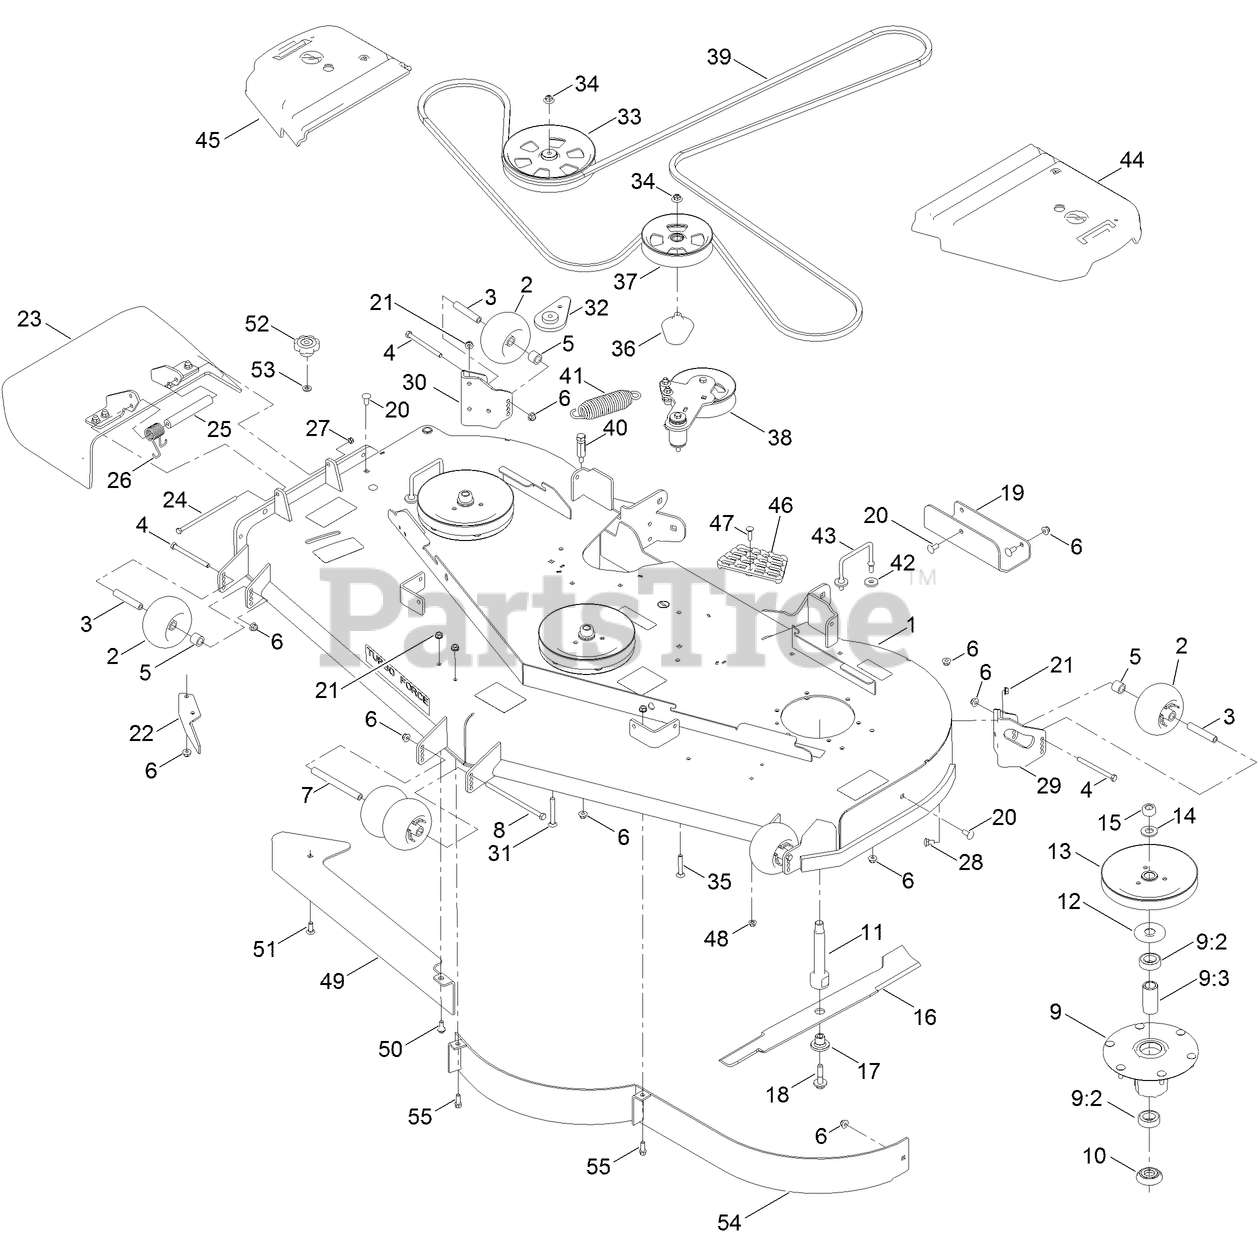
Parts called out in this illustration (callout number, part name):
1	DECK DECAL ASM
2	ROLLER-SCALP, ANTI
3	TUBE-SPANNER
4	SCREW-HH
5	TUBE-SPACER
6	NUT-HF, NI
7	SPACER-WHEEL
8	SCREW-HH
9	SPINDLE ASM
9:2	BEARING-BALL
9:3	SPACER-BEARING
10	GUARD-BOTTOM
11	SHAFT-SPINDLE
12	GUARD-BEARING, TOP
13	SHEAVE-DRIVE, BLADE
14	WASHER
15	NUT-HEX
17	BUSHING-HEX
18	SCREW-SEMS
19	PLATE-SKID
20	SCREW-CARR
21	NUT-HHF, WHIZ
22	BAFFLE-DISCHARGE
23	RUBBER DEFLECTOR ASM
24	SCREW-HH
25	SPACER
26	SPRING-TORSION
27	NUT-LOCK, NI
28	SCREW-CARR
29	MOUNT-WHEEL, LH
30	MOUNT-WHEEL, RH
31	SCREW-CARR
32	SPACER-IDLER
33	PULLEY-IDLER,FLAT
34	NUT-FLANGE, NI
35	BOLT-CARR, SHORT NECK
36	SPACER-PULLEY
37	PULLEY-IDLER, FLAT
38	IDLER ARM ASM
39	BELT-V
40	ANCHOR-SPRING, TALL
41	SPRING-EXTENSION
42	WASHER
43	WIREFORM-COVER
44	COVER-BELT, LH
45	COVER-BELT, RH
46	STEP-DECK
47	SCREW-CARR
48	NUT-HF, NI
49	PLATE-BAFFLE
50	BOLT-SHOULDER
51	SCREW-CARR
53	WASHER-HARDENED
